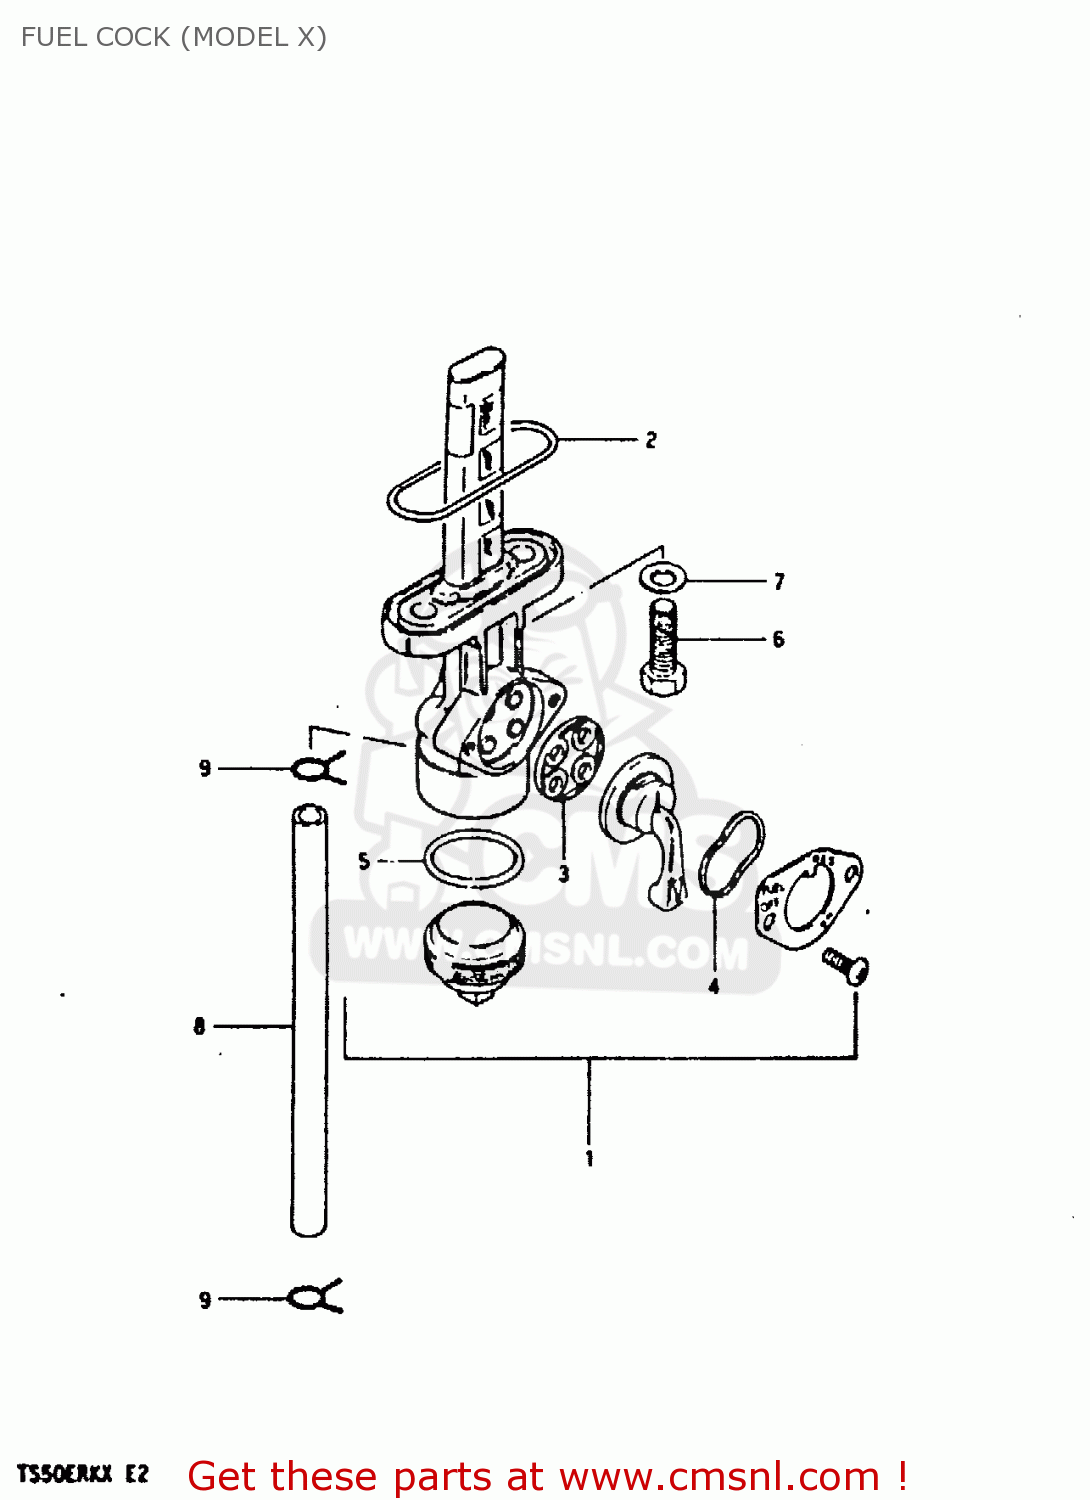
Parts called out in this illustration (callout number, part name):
1	COCK ASSEMBLY,FUEL
2	O RING,FUEL COCK
3	GASKET,LEVER (NAS)
4	WASHER,LEVER
5	GASKET,FILTER (NAS)
6	BOLT(6X20)
7	GASKET
8	HOSE
9	CLIP
